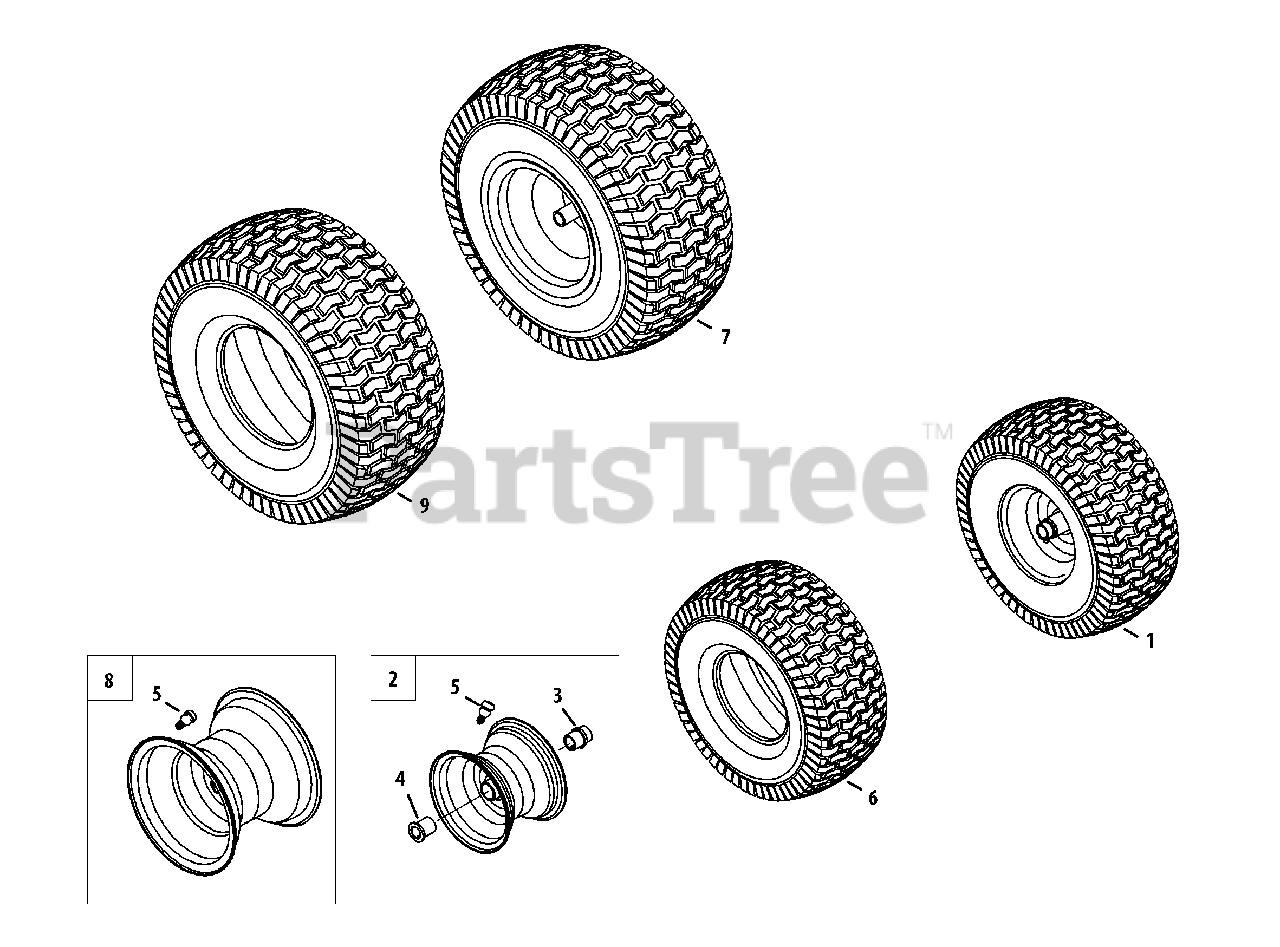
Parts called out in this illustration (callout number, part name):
1	Wheel Ass’y, Complete, 15 x 6 x 6
2	Rim Ass’y, 6.0 x 4.5, Flange Bearings
3	Bearing, Flange, .760 ID w/ Fitting
4	Bearing, Flange, .760 x 1.00 x 1.20
5	Valve, Tubeless Air
6	Tire, 15 x 6 x 6 Sq Shoulder
7	Wheel, Complete, 20 x 8 x 8
8	Rim Ass’y, 8.0 x 7.0 x .750 ID
9	Tire, 20 x 8 x 8 Sq Shoulder
